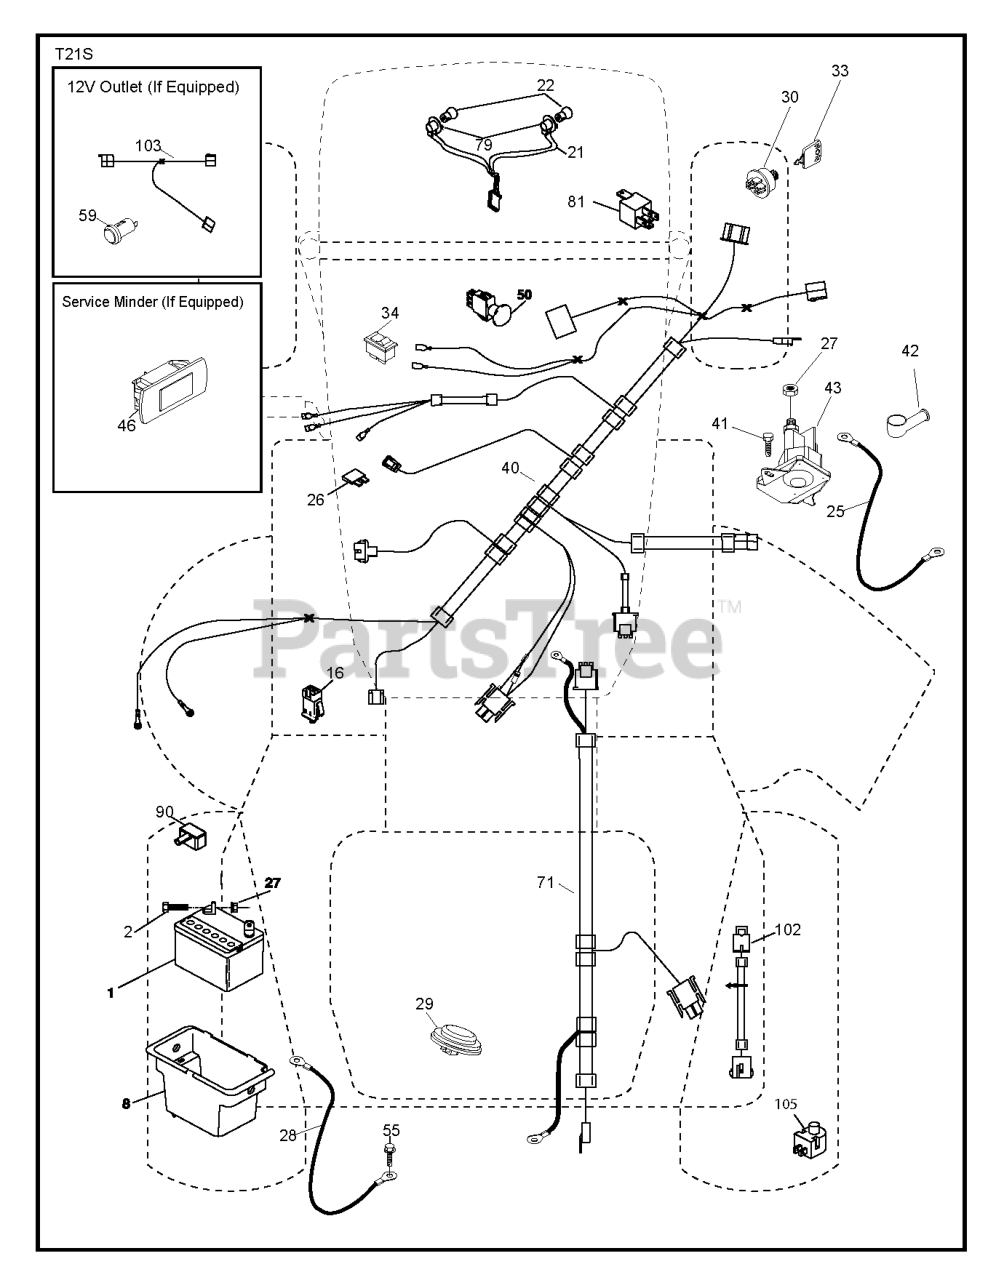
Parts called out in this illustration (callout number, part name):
1	REPL BY 532 12 38-99
2	BOLT.HEX.1/4.X.3/4.DICHROMATE
8	BOX.BATTERY.MNT.REAR.L
16	SWITCH INTERLOOK PUSH-IN
21	HARNESS.LIGHT W/4152J BULBS
22	LIGHTBULB
25	CABLE.STARTER.8GA.17.5
26	FUSE 20AMP
27	NUT
28	CABLE.GROUND.REAR.BATTERY.8G
29	SWITCH.SEAT.DELTA.OPC.
30	SWITCH.IGN.DELTA.W.LGH.ROS
33	KEY.CHAIN.BLISTER.PACK.GEN.USA
34	SWITCH LT
40	HARNESS.IGN.ELEC.RELAY.TEX.46
41	SCREW
42	TERMINAL COVER
43	SOLENOID.STARTER.BRASS.PLUNGER
46	GUAGE.SRVCMNDR.HRMTR.
50	SWITCH.PTO.8TERMINAL.STD.BLK
55	SCREW 5/16"
71	HARNESS.CHASS.8AWG.REAR.BATTER
79	BULB HOLDER ASM.
81	RELAY HARNESS.SEALED
90	COVER.TERMINAL.BATTERY
102	HARNESS PIGTAIL PCH TEX ROS
105	REVERSE SWITCH
